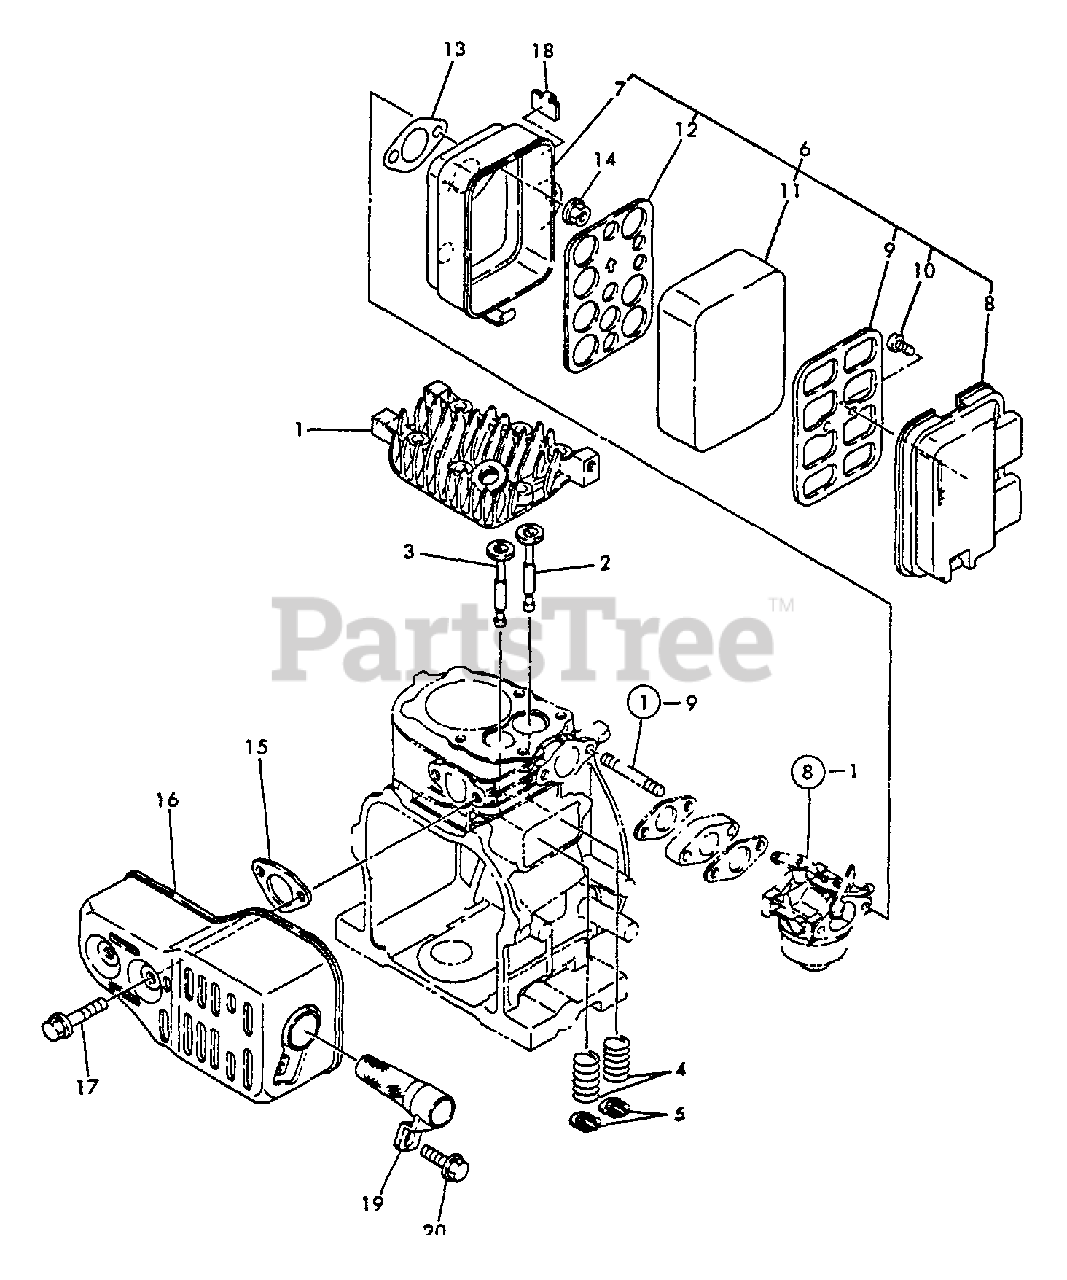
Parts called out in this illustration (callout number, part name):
1	HEAD, CYLINDER
2	VALVE, INTAKE
3	COVER, CRANKCASE
4	SPRING, VALVE
5	RETAINER, VALVE
6	AIR CLEANER ASSY
7	CASE, AIR FILTER
8	COVER, AIR FILTER
9	HOLDER (B), ELEMENT
10	SCREW - 5X10
11	FILTER, AIR
12	HOLDER (A), ELEMENT
13	GASKET, INTAKE
14	NUT - 6 -- FLANGE
15	GASKET, EXHAUST
16	MUFFLER
17	BOLT - 6X45
18	CLAMP
19	SCREEN, SPARK ARRESTOR
20	BOLT - 6X8 -- PLATED
